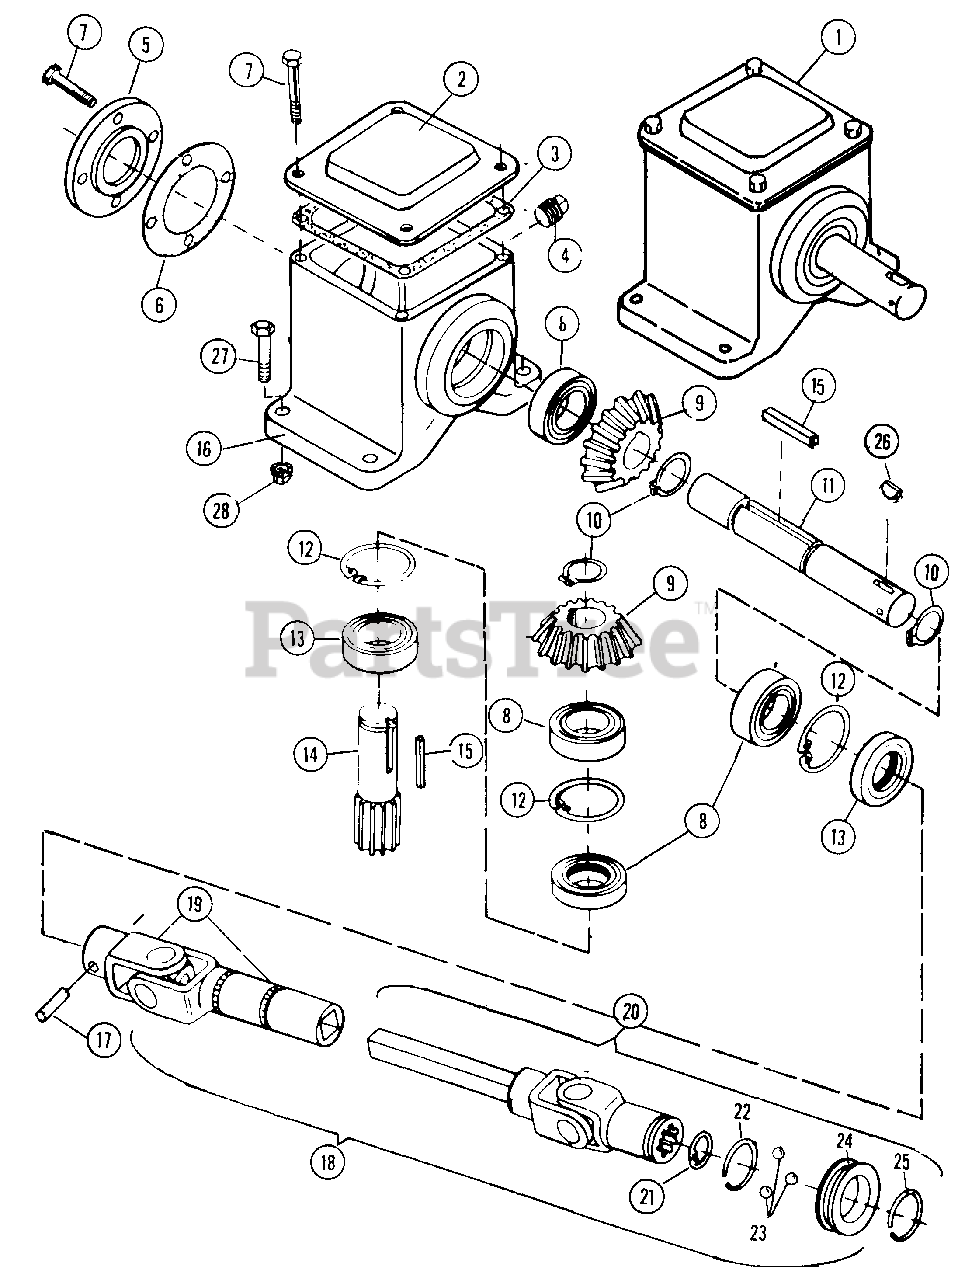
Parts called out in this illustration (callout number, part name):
1	(NLA) GEAR BOX ASSEMBLY
2	COVER, GEAR BOX (TOP)
3	GASKET, COVER
4	(NLA) PLUG, 1/2" P.T.
5	(NLA) COVER, GEAR BOX (SIDE)
6	SHIM, SIDE COVER
7	BOLT, 1/4C x 3/4 HEX HEAD
8	BEARING, BALL
9	PINION-GEAR
10	RING, RETAINING
11	SHAFT, GEAR BOX INPUT
12	RING, RETAINING
13	SEAL, OIL
14	SHAFT, GEAR BOX OUTPUT
15	KEY, STRAIGHT
16	(NLA) HOUSING, GEAR BOX
17	(NLA) PIN, GROOVE 1/4 x 1-3/4
18	UNIVERSAL JOINT ASSEMBLY
19	(NLA) JOINT & TUBE ASSEMBLY
20	(NLA) JOINT & SHAFT ASSEMBLY
21	(NLA) RING, RETAINING
22	RING, SPRING RETAINING
23	BALL, 3/8" DIAMETER
24	COLLAR, LOCK
25	RING, RETAINING
26	KEY, WOODRUFF
27	BOLT, 3/8-16 x 1-1/4 HEX HEAD
28	NUT, 3/8-16 HEX FLANGE LOCK
